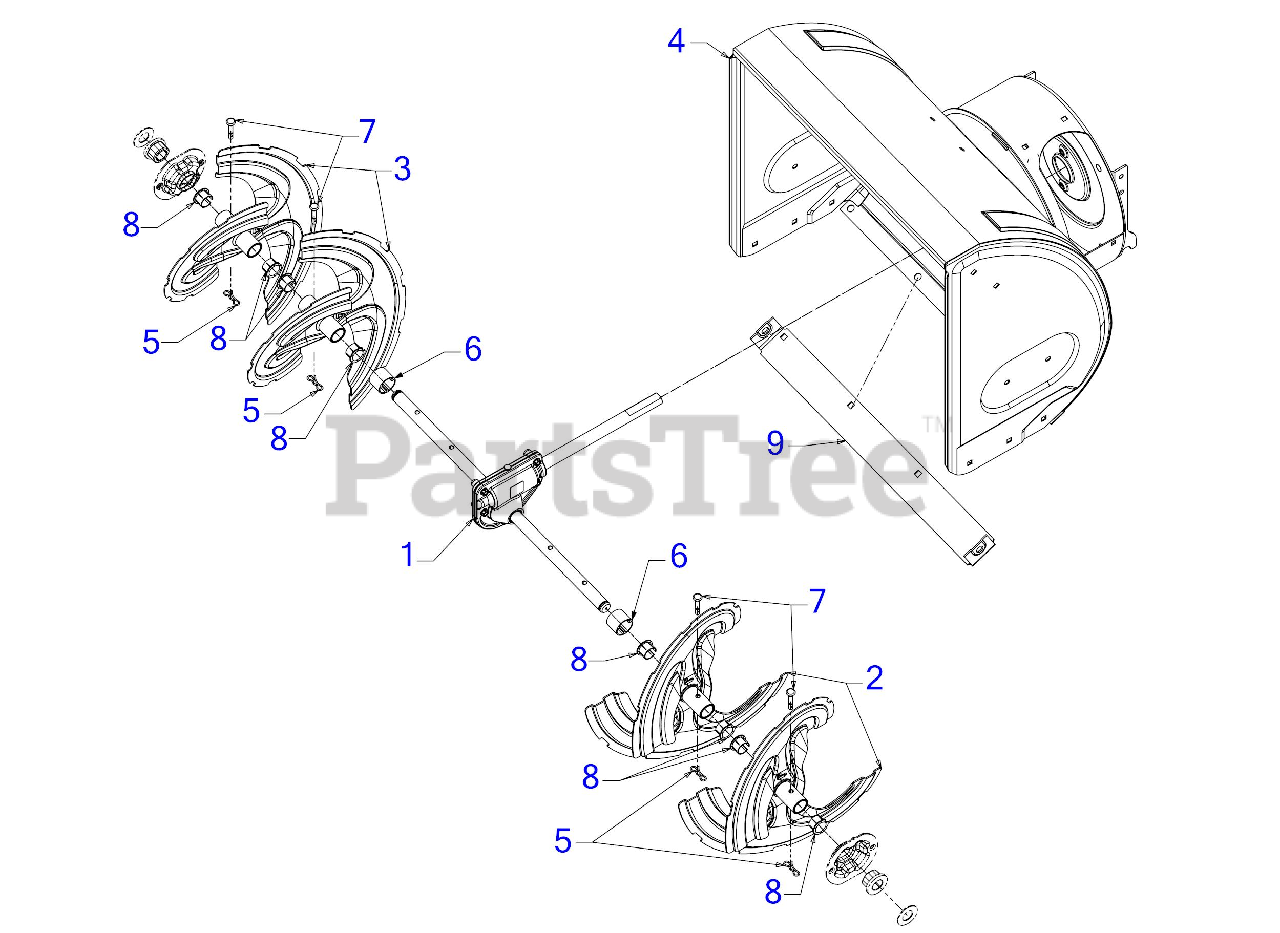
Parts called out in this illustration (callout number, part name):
1	22" GEARBOX ASSEMBLY
2	AUGER ASSEMBLY (LH)
3	AUGER ASSEMBLY (RH)
4	22" AUGER HOUSING ASSEMBLY
5	BOW TIE COTTER PIN 1/4-5/16
6	SPACER 1.25OD x .75ID X1.00 LG
7	SHEAR PIN .25 x 1.50 GR2
8	FLANGE BUSHING
9	22" SHAVE PLATE
